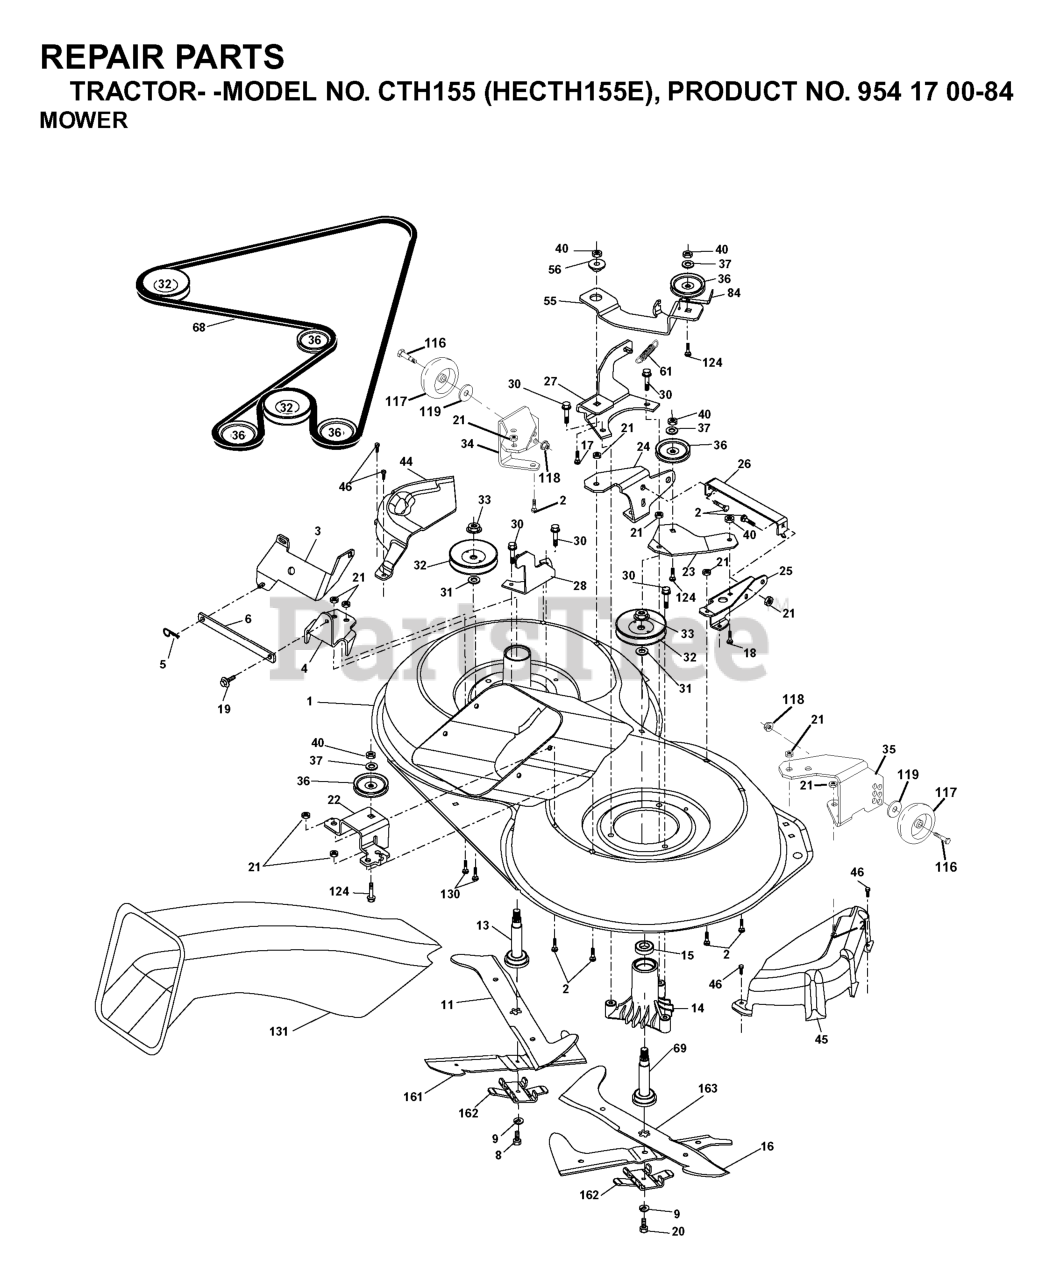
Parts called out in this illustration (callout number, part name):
1	MOWER HOUSING, DECK
2	RP BOLT 5/16-18 X3/4 ZN/YEL GR
5	RETAINER-SPRNG RB
6	BAR.SWAY.92.CRD
8	BOLT.3/8-24X1.25 GR8
9	LOCKWASHER
11	BLADE-LH 5PT STAR(CTH130)
13	SHAFT ASM VENT
14	HOUSING.MANDREL.VENTED (MACHD)
16	BLADE RH 6PT STAR(CTH130)
17	BOLT.3/8-14X1.25
19	BOLT SHD 5/16-18
20	BOLT.3/8-24X1.25GR8. LHTHRD
21	LOCKNUT
26	BRACE.SUPT.SUSP.FRT.CRD
30	SCREW, WASHER HEAD
31	WASHER
32	PULLEY, MANDREL
33	NUT, FLG TOPLOCK 9/16"
36	PULLEY.IDLER.4.25
37	WASHER
45	COVER.MANDREL.RH.CRD
46	SCREW.1/4-20X5/8
56	SPACER.RETAINER.MOWER
61	SPRING.TENSION.BELT
68	HEX-BELT
69	SHAFT.ASM.W/LWR.BRG.RH.THREAD
84	KEEPER, BELT IDLER
116	SHOULDER BOLT
117	WHEEL GAGE DONUT
118	LOCKNUT
119	WASHER.5/16.FLAT.STE.STD.
124	BOLT.3/8-16X1.50
130	BOLT.CARR.SQNK.5/16-18UNC.X3/4
131	CHUTE BAGGER
